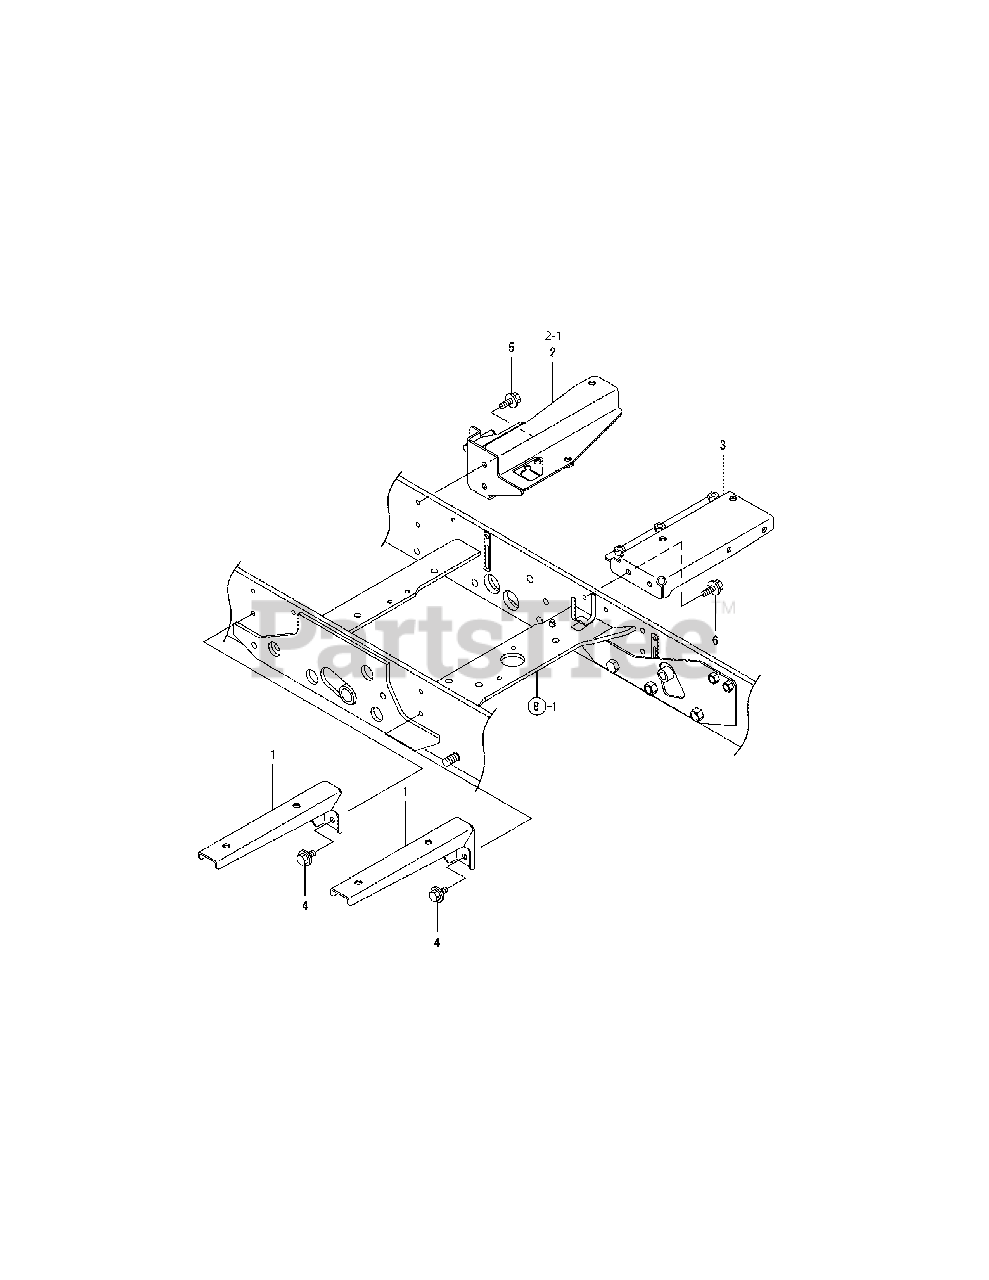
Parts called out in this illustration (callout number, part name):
1	STAY L, STEP CMP
2	STAY RF, STEP CMP
2-1	STAY RF, STEP CMP
3	STAY RR, STEP CMP
4	BOLT M 8X 16 PLATED
5	BOLT M 8X 16 PLATED
6	BOLT M 8X 16 PLATED
